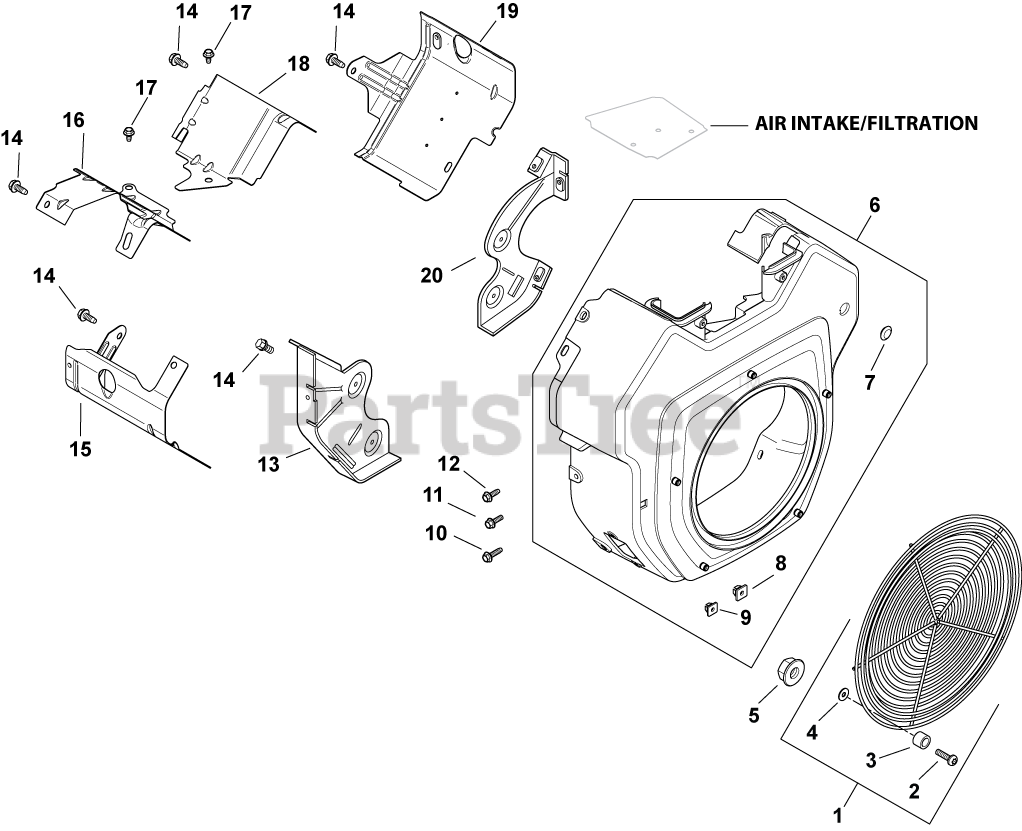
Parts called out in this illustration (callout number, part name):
1	KIT, GRASS SCREEN GUARD
2	SCREW, SPECIAL HEAD
4	WASHER, FLAT 1/4" (O.D. 5/8")
6	KIT, BLOWER HOUSING ASSEMBLY USE 24 027 477-S
7	NUT, PLASTIC (KM)-USE 25 100 37-S
8	PLUG, BUTTON 9/16
9	NUT, PLASTIC
10	SCREW, FLG THD FRM M5X.8X20-(#25086399S)
11	SCREW, HVY FLG M5X.8X16
12	SCREW,FLG THD FRM M5X0.8X16-(#25086398S)
13	PLATE, BACKING - DISCONTINUED
14	SCREW,FLG THD FRM M6X1.0X16-(#25086397S)
15	BAFFLE, LEFT BARREL -USE 24 063 88-S
16	BAFFLE, VALLEY #2 SIDE-USE 24 063 94-S
17	SCREW, FLG THD FRM M5X.8X10
18	BAFFLE, VALLEY (CH)-USE 24 063 93-S
19	KIT, CYL BAFFEL #1 SIDE
20	PLATE, BACKING #2 SIDE
